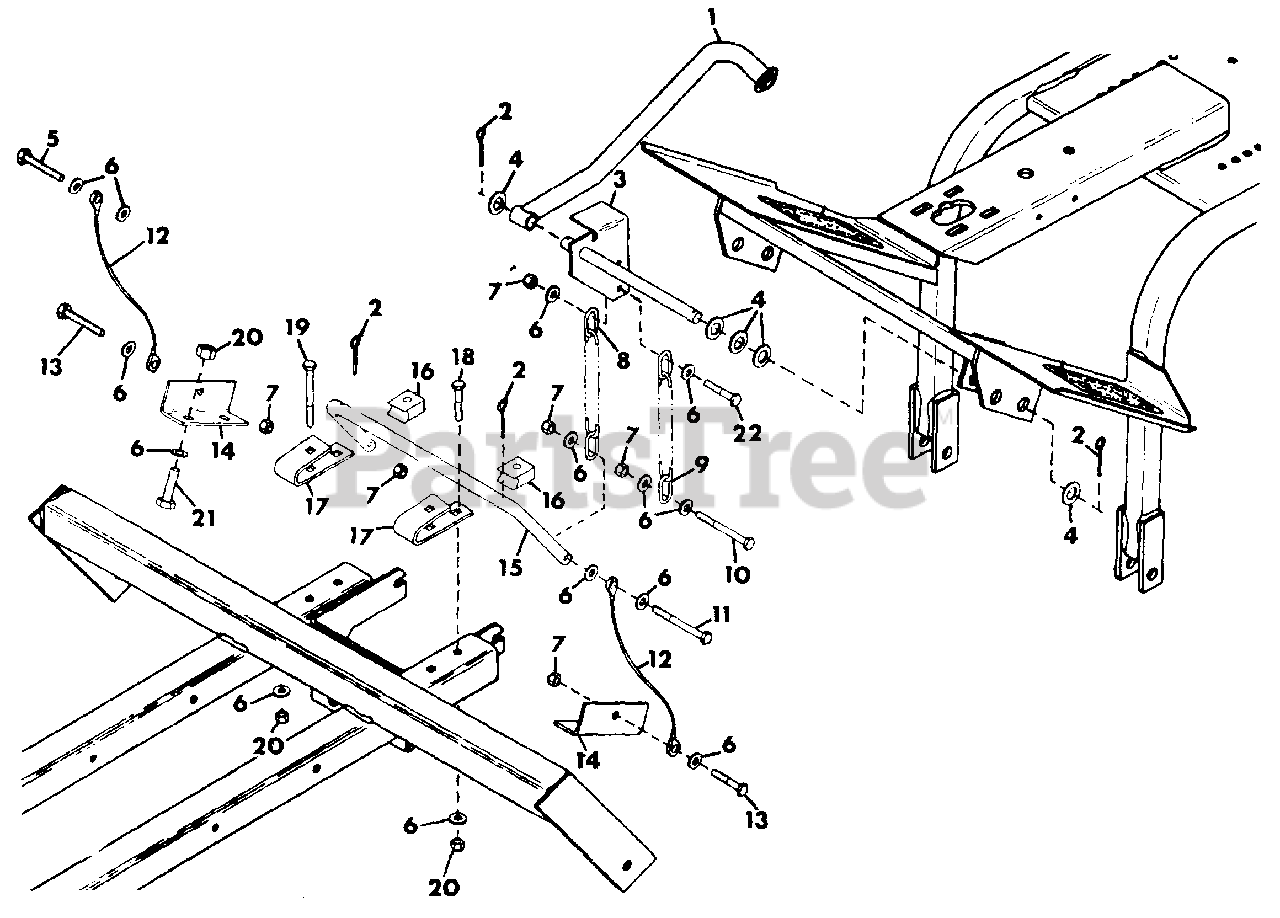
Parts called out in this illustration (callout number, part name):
1	WELDMENT, LIFT LEVER
2	PIN, COTTER .12X1.25
3	WELDMENT, LIFT BRACKET
4	WASHER, FLAT .656X1.250X.100
5	BOLT, HEX 5/16-18X1.75
6	WASHER, FLAT .406X.812X.065
7	NUT, LOCK 5/16-18
8	CHAIN, LIFT(8-LINK)
9	CHAIN, LIFT(7-LINK)
10	BOLT, HEX 5/16-18X3.25
11	BOLT, HEX 5/16-18X2.00
12	CABLE, LIFT
13	BOLT, HEX 5/16-18X1.00
14	BRACKET, LIFT
15	ARM, PIVOT
16	STOP, NYLON
17	BRACKET, AXLE SUPPORT
18	BOLT, HEX 3/8-16X3.00
19	BOLT, HEX 3/8-16X4.00
20	NUT, LOCK 3/8-16
21	BOLT, HEX 3/8-16X1.00
22	BOLT, HEX 5/16-18X1.25
